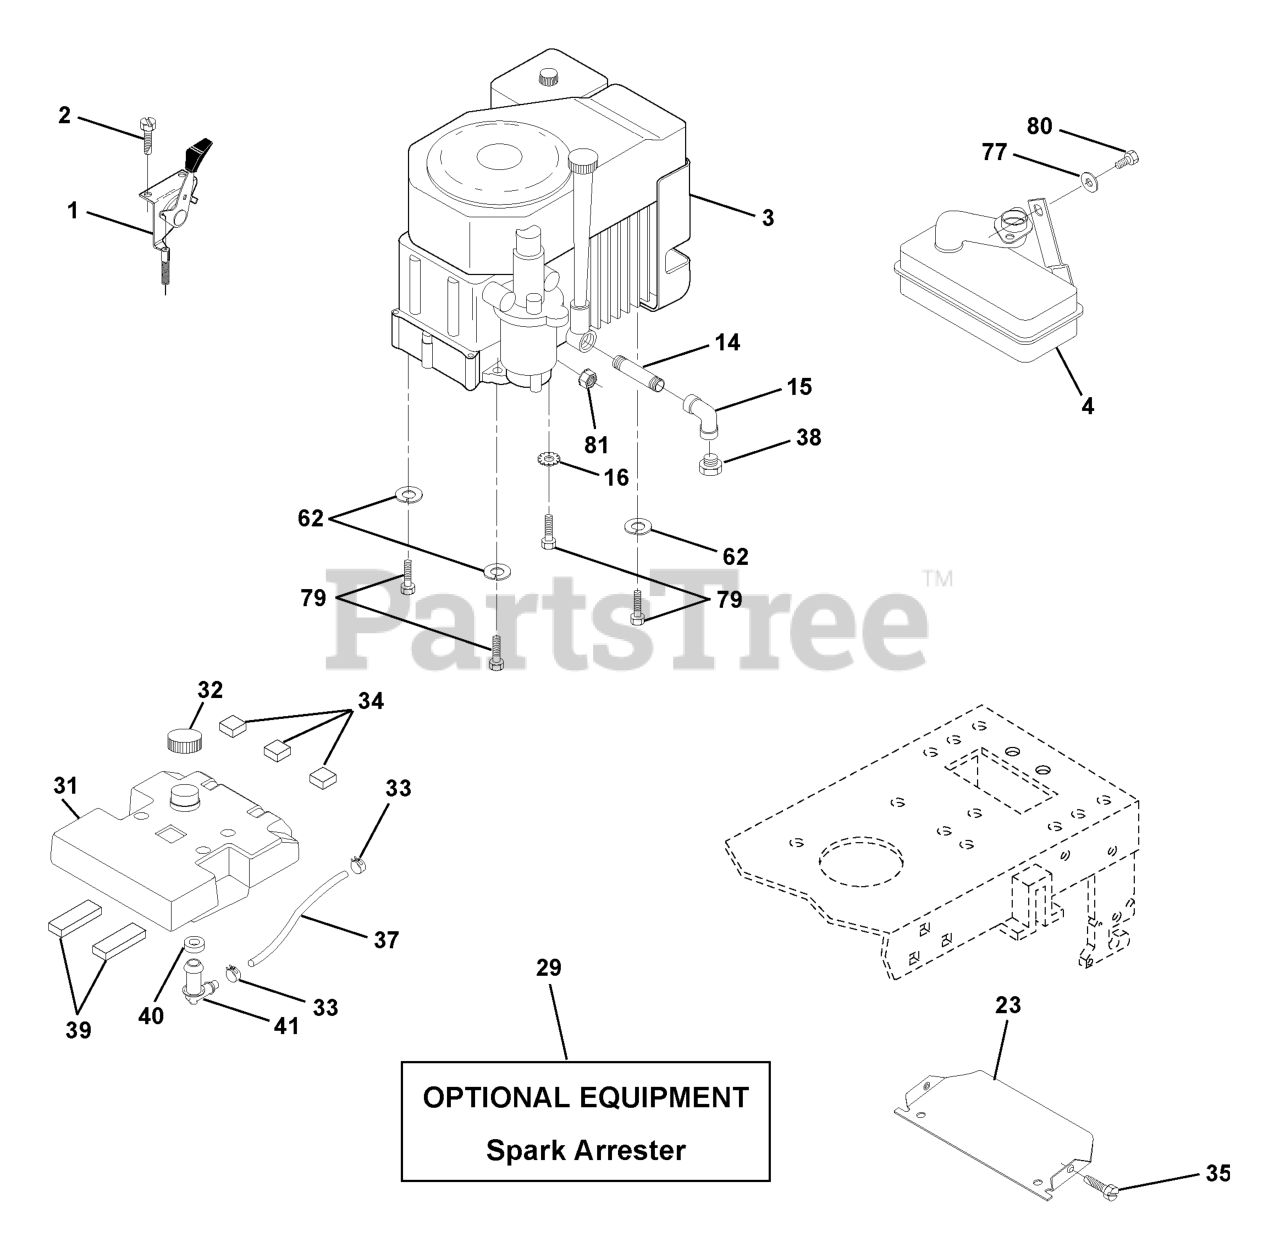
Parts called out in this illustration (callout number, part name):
1	CONTROL SWITCH 27 LH
2	SCREW LT
3	Engine Kohler
4	MUFFLER LT 12.5
14	Nipple Pipe 3/8 Npt X 3-1/2
15	ELBOW
16	WASHER EXT TOOTH LOCK 5/16
23	SHIELD HEAT
29	KIT.SPARK ARRESTOR 794945 B&S
31	TANK.FUEL(3.5.GAL)
32	FUEL CAP
33	HOSE CLAMP
34	PAD-SPACER LT
35	SCREW.THDROL.5/16-18X3/4.TTY
37	HOSE T
38	Plug Oil Drain
39	PAD IDLER TI
40	BUSHING OUTLET T
41	STEM FUEL TANK
62	WASHER.LOCK.HVY.HLCL.SPR.5/16
77	WASHER
79	BOLT, HEX
80	Bolt Hex Hd. 5/16-18unc x 1/2
81	NUT FLANGE 1/4-20 STARTER NUT
